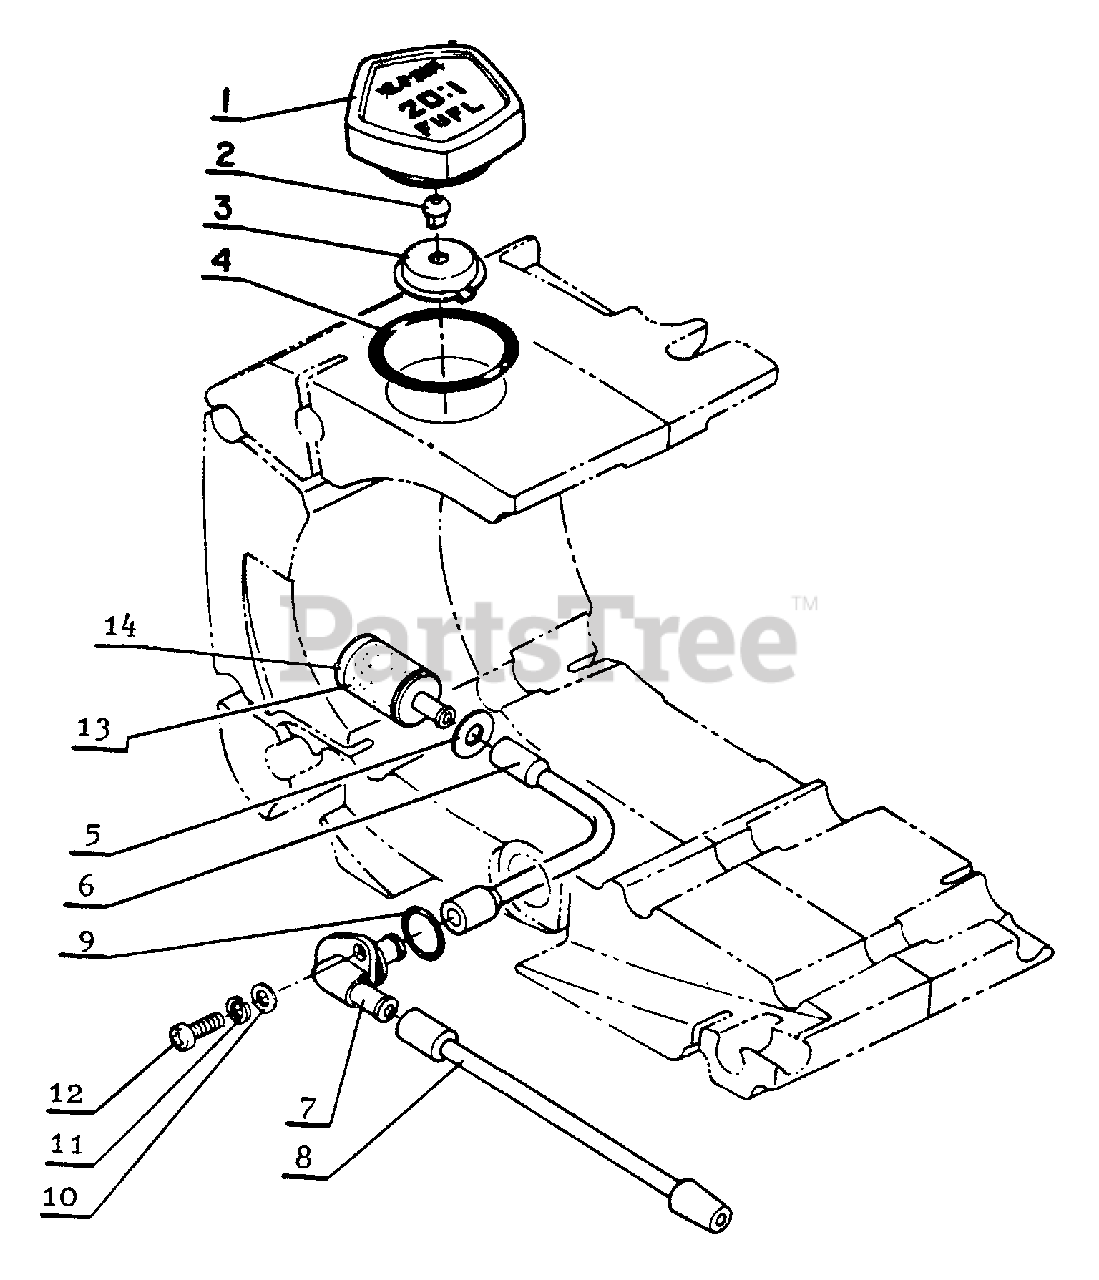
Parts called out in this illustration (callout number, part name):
1	CAP ASSY
2	VALVE, CHECK
3	HOLDER, VENT
4	O-RING 29
5	WASHER 6.5×11.5×0.8
6	PIPE, FUEL - INNER
7	CONNECTOR, PIPE
8	PIPE, FUEL - OUTER
9	O-RING 12 MM
10	WASHER 4 MM
11	WASHER, SPRING 4 MM
12	SCREW 4×8
13	FILTER, FUEL
14	FUEL STRAINER COVER
